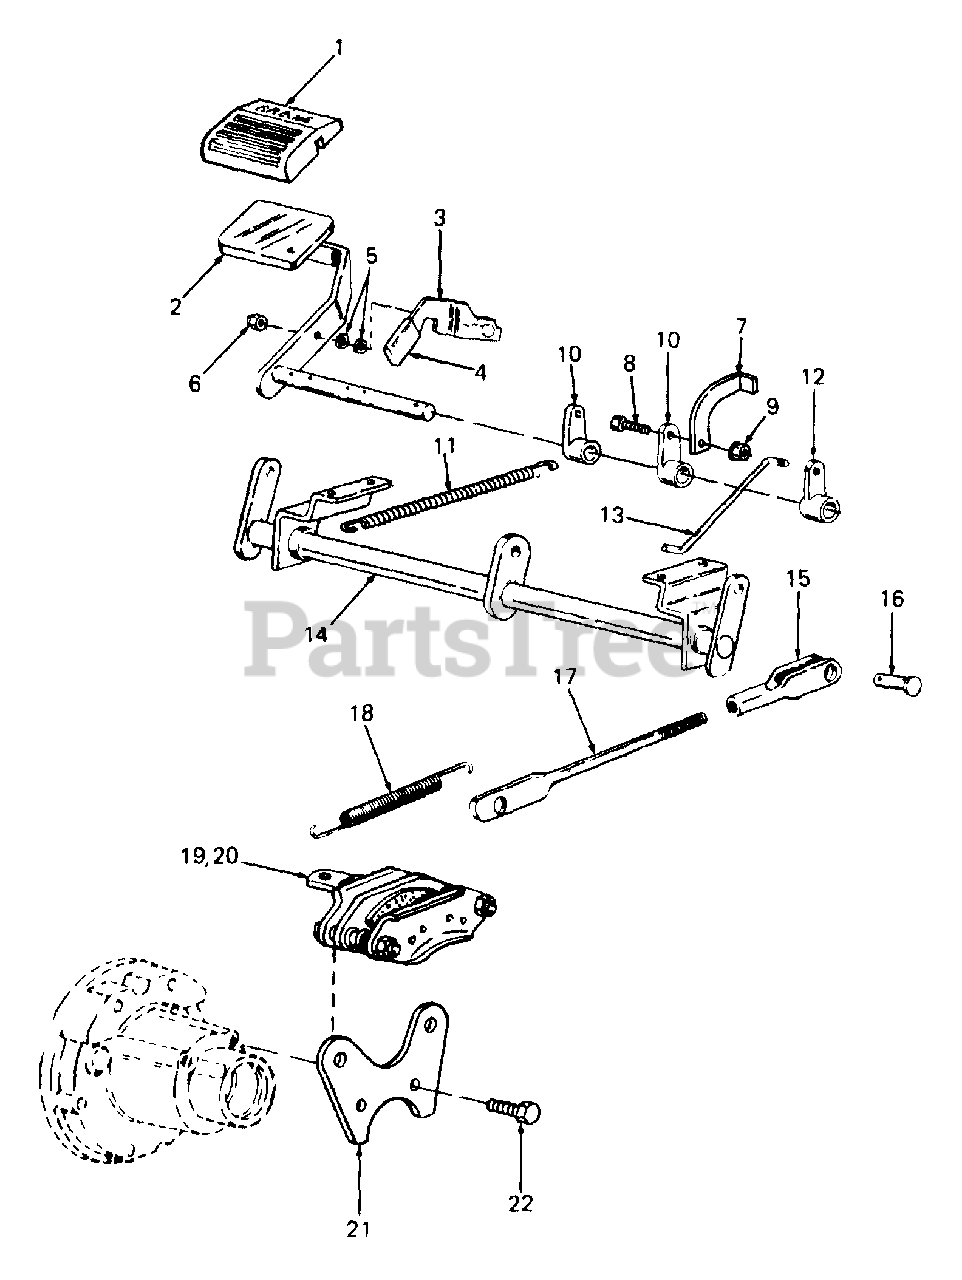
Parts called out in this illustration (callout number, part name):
1	Pad, Brake Pedal
2	Pedal Assy, Brake
5	Washer, Wave, 1/4 Dia
6	Nut, Hex Insert Lock, 1/4-20
8	Screw, Hex Cap, 3/8-16 X .75 Lg GR5
9	Nut, Hex Flanged Lock, 3/8-16 GR5
11	Spring, Return
15	Clevis, Adjustment
16	Pin, Clevis, 3/8 Dia X 1.0 Lg
17	Rod, Brake
18	Spring, Tension
19	Brake Kit, RH Caliper
21	Bracket, Brake Mounting
22	Screw, Hex Cap, 5/16-18 X 1.0 Lg GR5
